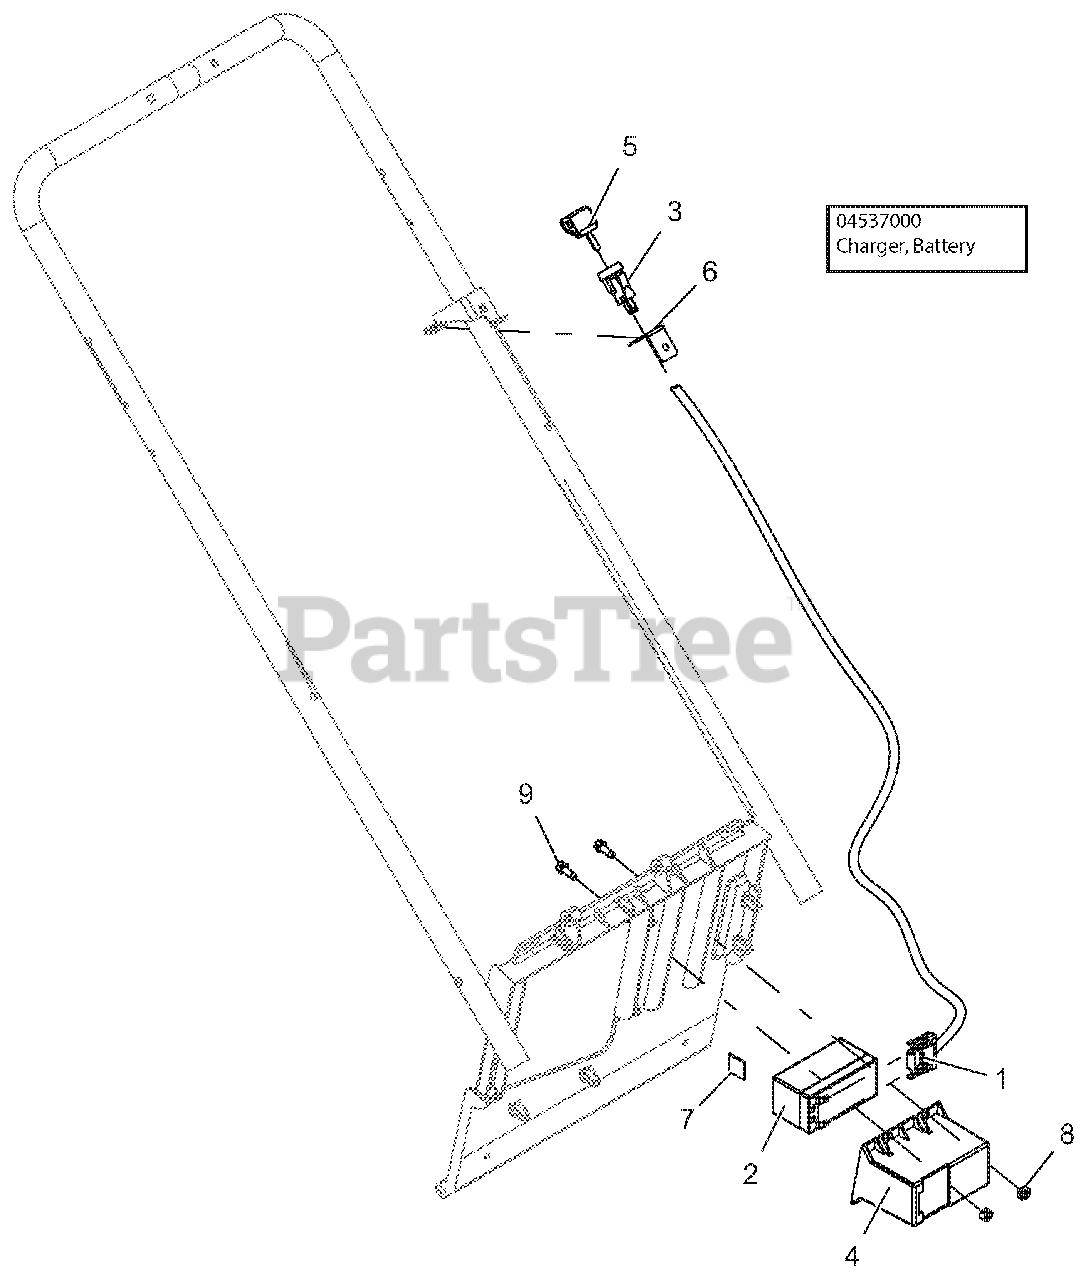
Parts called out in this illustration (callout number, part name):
1	HARNESS, ELEC START - SUBARU
2	BATTERY, SMALL AGM
3	SWITCH, KEY
4	COVER, BATTERY
5	KEY, LM ELEC START
6	BRKT, KEY SWITCH
8	NUT-LK-CTR .25-20 YWZC
9	SCR-TAP .25-20 x .62 HWH TR YWZ
